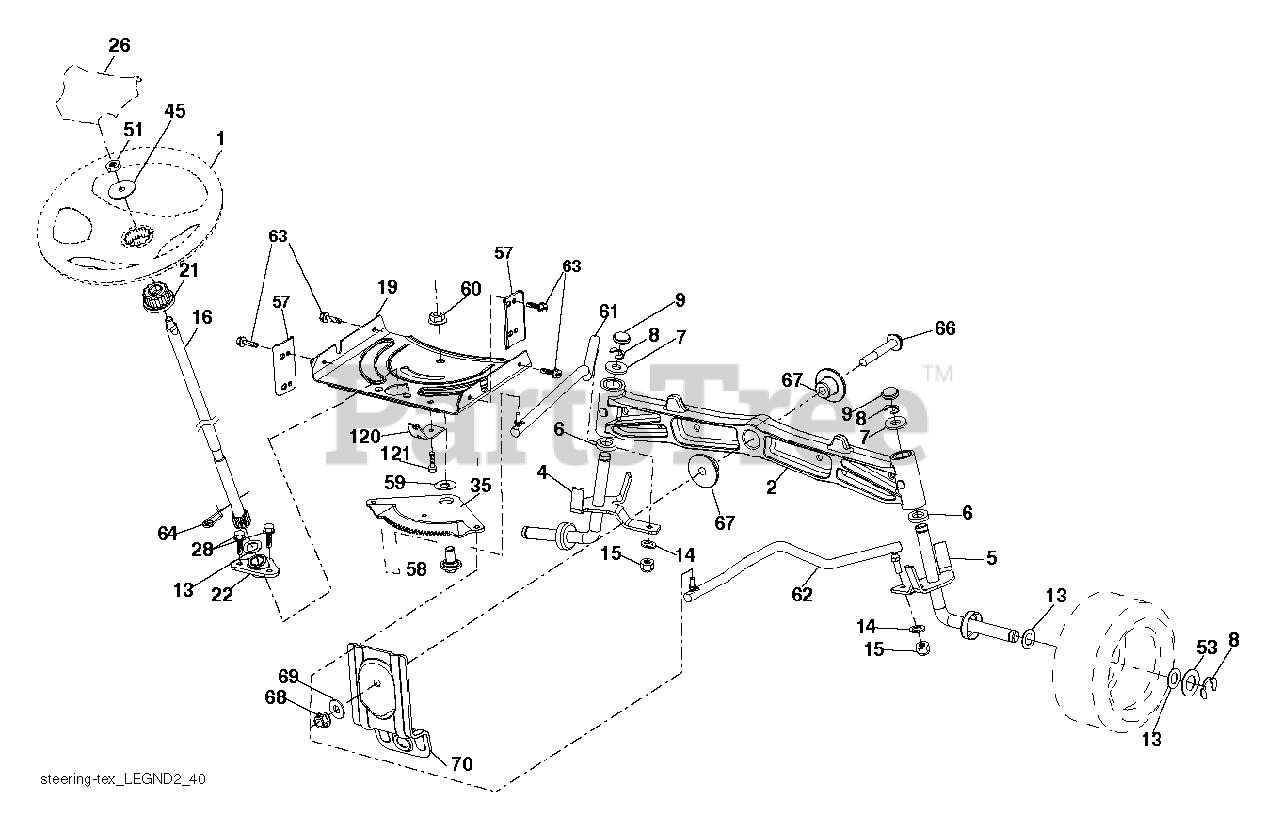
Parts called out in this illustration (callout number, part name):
1	WHEEL.STEERING.HUSQ.PREM.HRDRM
2	AXLE.CAST.IRON
4	SPINDLE.WELDED.LH.15"TEX
5	SPINDLE.WELDED.RH.15"T
6	THRUST WASHER
9	CAP.SPINDLE.BLACK
14	WASHER, LOCK 3/8
15	NUT CROWNLOCK 3/8-24
16	SHAFT, STEERING
19	PLATE.STEER.DDL.NLT/NG
21	ADAPTER, WHEEL STNG..
22	STEERING.SUPT.LOWER.
26	INSERT.CAP.WHL.STRG.HUSQ.PREM
28	SCREW, 3/8-16X3/4
35	GEAR.SECTOR.PLATE.DDL.
45	WASHER 9/16"ID, 2 3/8"OD
51	NUT.HEX.1/2-20
53	WASHER.HARDENED
57	BRACKET.UPSTOP.TEX
58	BOLT.SHOULDER.SECTOR.P
59	WASHER.THURST.SECTOR.S
60	NUT FLANGE LOCK 5/8-11
61	DRAGLINK.LH.BALLSTUD.D
62	DRAGLINK.RH.BALLSTUD.D
63	SCREW
64	RETAINER.CLIP.SPRING.S
66	BOLT HEX FGHD 7/16-14 X 3 SERR
67	BUSHING.PM.FRONT AXLE
68	NUT.LOCK.FLANGE.7/16
69	WASHER.1.5X.505X.118
70	BRKT.DECK.SUSPENSION.F
120	BRKT.LOCATOR.CBL.BRAKE.VARIATO
121	SCREW LT
